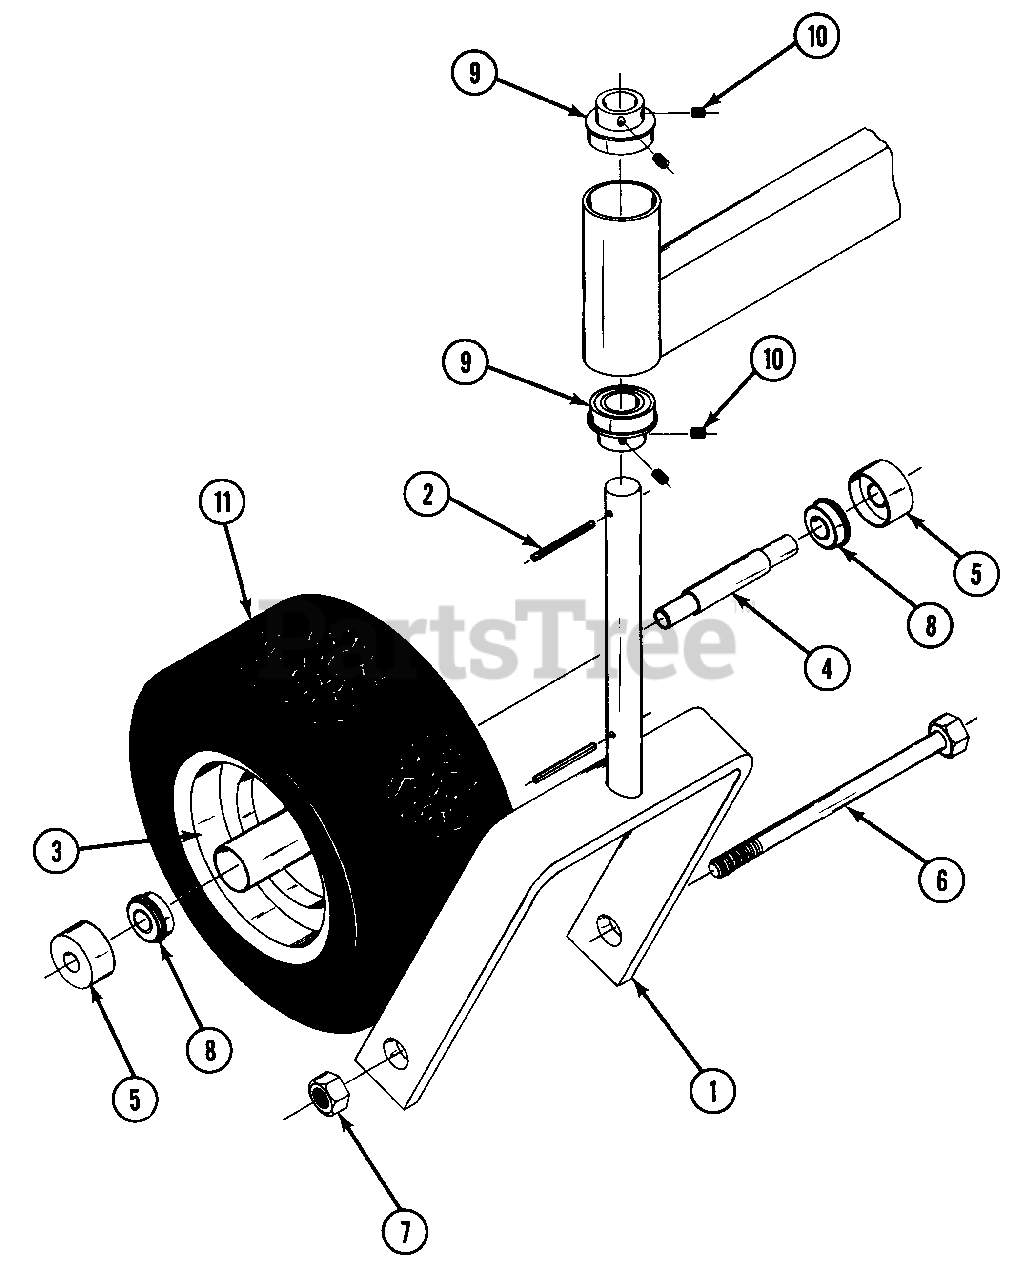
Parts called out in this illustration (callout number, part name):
1	CASTER WELDMENT
2	PIN, SPIROL, 3/16 X 2, LIGHT DUTY
3	WHEEL 410 X 350-4, 2 PLY, W/RIM
4	SPACER, BEARING
5	SHIELDS BEARING
6	CAPSCREW, 5/8-11 X 7.5, GRADE 5
7	LOCKNUT, 5/8-11, TOPLOCK 3/8
8	BEARING, 5/8 I.D. X 1-3/8 O.D.
9	BEARINGS 1" BORE
10	SETSCREW, 1/4-28 X 5/16
11	TIRE, 410/350 X 4
